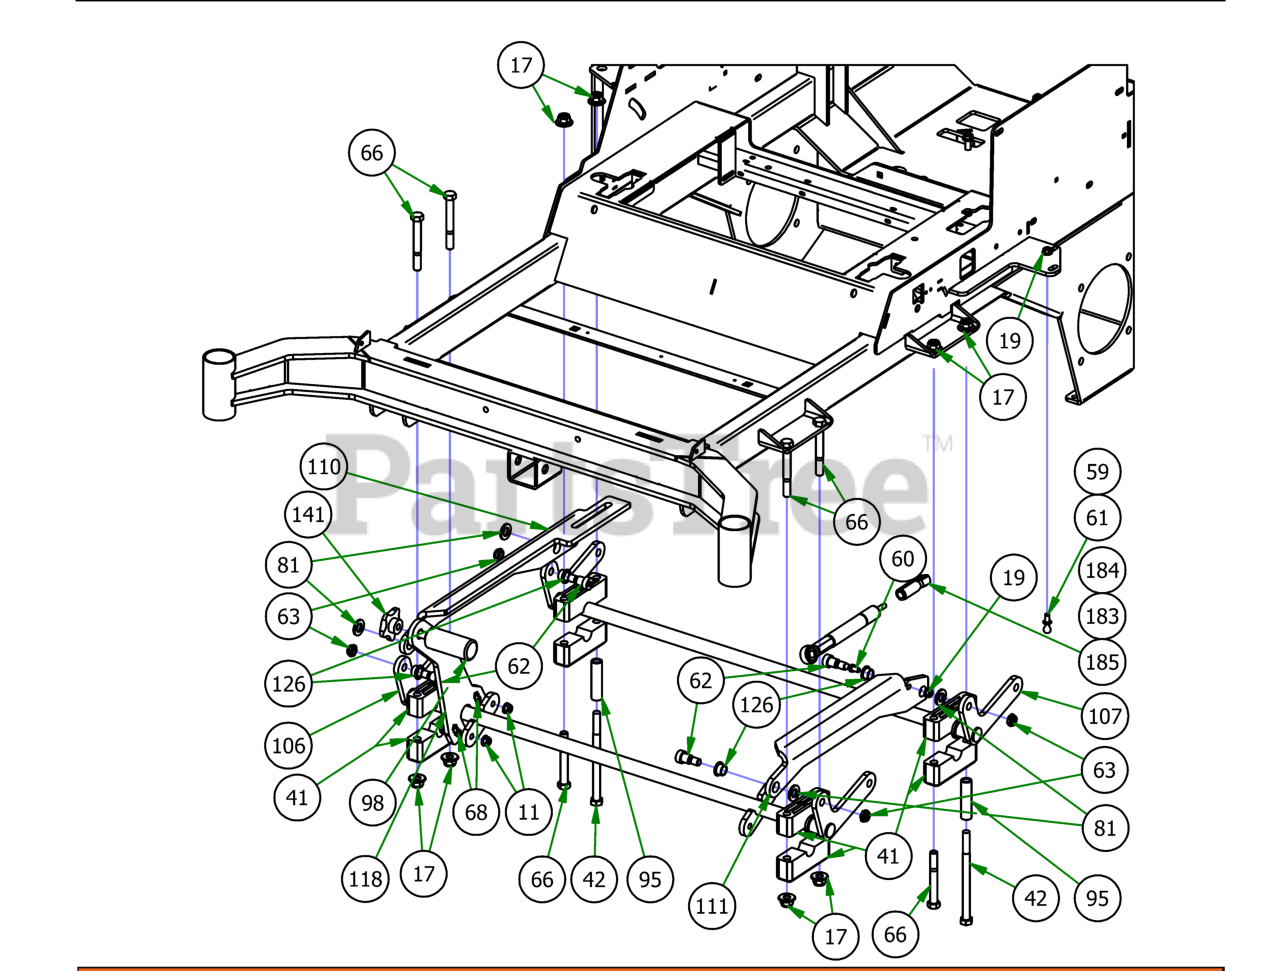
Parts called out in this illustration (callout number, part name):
11	3/8" Nylock Flange Nut
17	1/2-13 NYLON INSERT FLANGE LOCKNUT ZINC
19	5/16" Flange Nut
41	Pillow Block Assembly
42	1/2 x 7 Hex Bolt Grade 5
59	13mm Damper Ball Stud-Steering
60	10mm Damper Ball Stud-Steering
61	10mm Damper Ball Stud-XP Linkage
62	5/8'' x 5/8'' Shoulder Bolt
63	1/2" Nylcock Nut (1/2 Jam)
66	1/2" x 4" Bolt (Grade 8)
68	3/8" x 1 1/4" Carriage Bolt
81	.630 ID Plastic Washer
95	2019 Deck Stop Spacer
98	Knurled Pedal
106	2019 Outlaw Actuator - Front
107	2019 Outlaw Actuator - Rear
110	2019 Actuator Linkage - Right
111	2019 Actuator Linkage - Left
118	Foot Lift Upright Lever
126	Bronze Bushing - SF - 2024-8
141	Foot Pedal Knob 1/2-13
169	2019 Rebel Frame - Powdercoated
183	200 lb Gas Spring- 54" Deck outlaw
184	250lb Gas Spring - 61" Deck
185	300lb Gas Spring - 72" Deck
